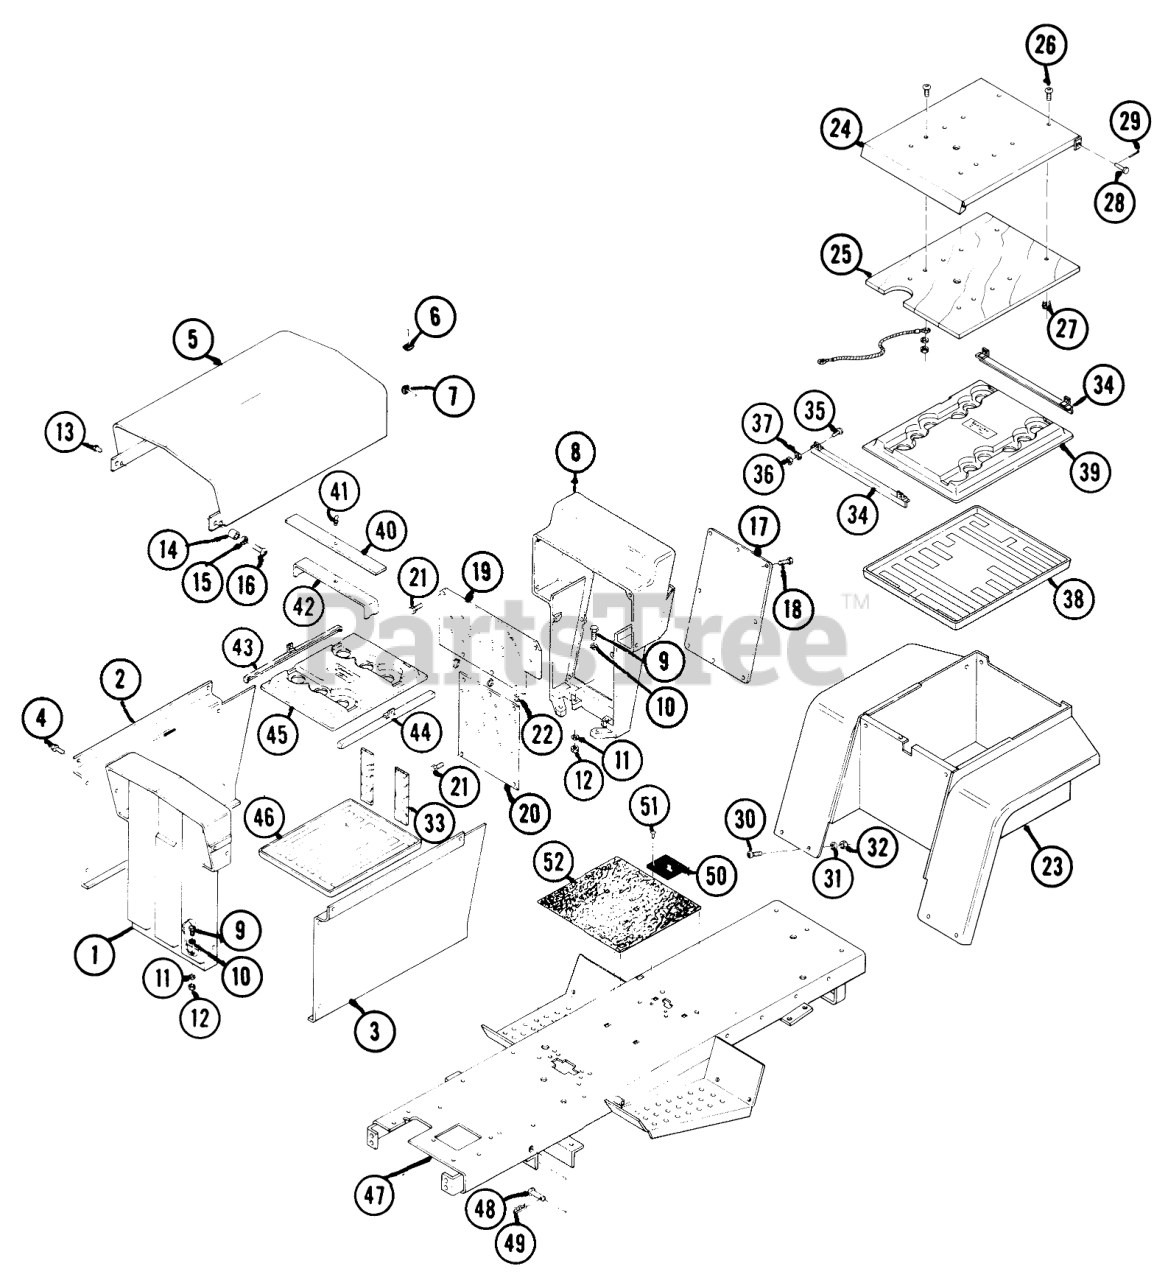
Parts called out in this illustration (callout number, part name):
7	BUMPER
13	Rivet
18	Screw, Thd. Rolling #8-32 x 3/8
20	Lower Control Panel
21	Thrd. Rolling Screw #8-32 x 1/2
23	Rear Body Assembly (with Fenders)
26	Screw, Phillips Pan Head 5/16-18 x 3/4
34	Battery Clamp, Rear Box
51	Rivet
